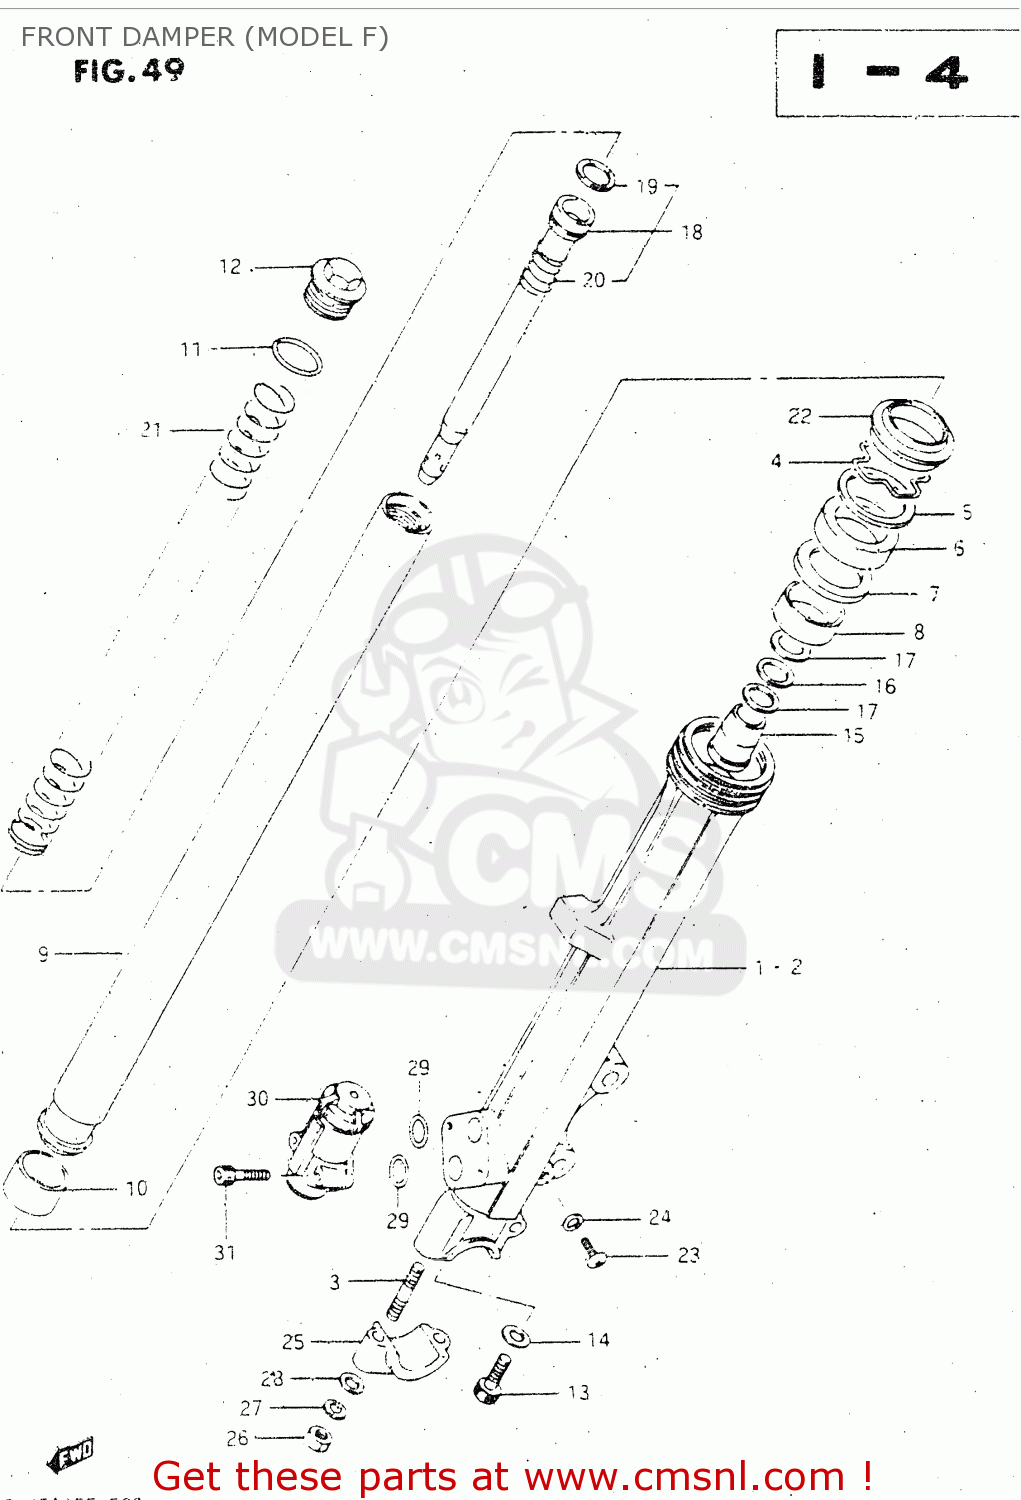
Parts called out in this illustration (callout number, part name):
1	TUBE,FORK,OUTER,RIGHT
2	TUBE,FORK,LEFT,OUTER
3	STUD 8X30
4	RING,STOPPER
5	WASHER. FRONT FORK
6	OIL SEAL,FRONT FORK
7	WASHER
8	METAL,SLIDE
9	TUBE,FORK INNER
10	METAL,FR FORK PISTON
11	O RING
12	CAP
13	BOLT,FORK CYLINDER(10X25)
14	GASKET (NAS)
15	PIECE,OIL LOCK
16	WASHER
17	SPRING,LEAF
18	CYLINDER,FRONT FORK
19	RING,PISTON
20	SPRING,REBOUND
21	SPRING
22	SEAL,DUST
23	SCREW
24	GASKET,DRAIN,PLUG (NAS)
25	HOLDER,AXLE
26	NUT
27	WASHER,LOCK,8.
28	WASHER
29	O RING
30	PDF ASSEMBLY
31	BOLT
